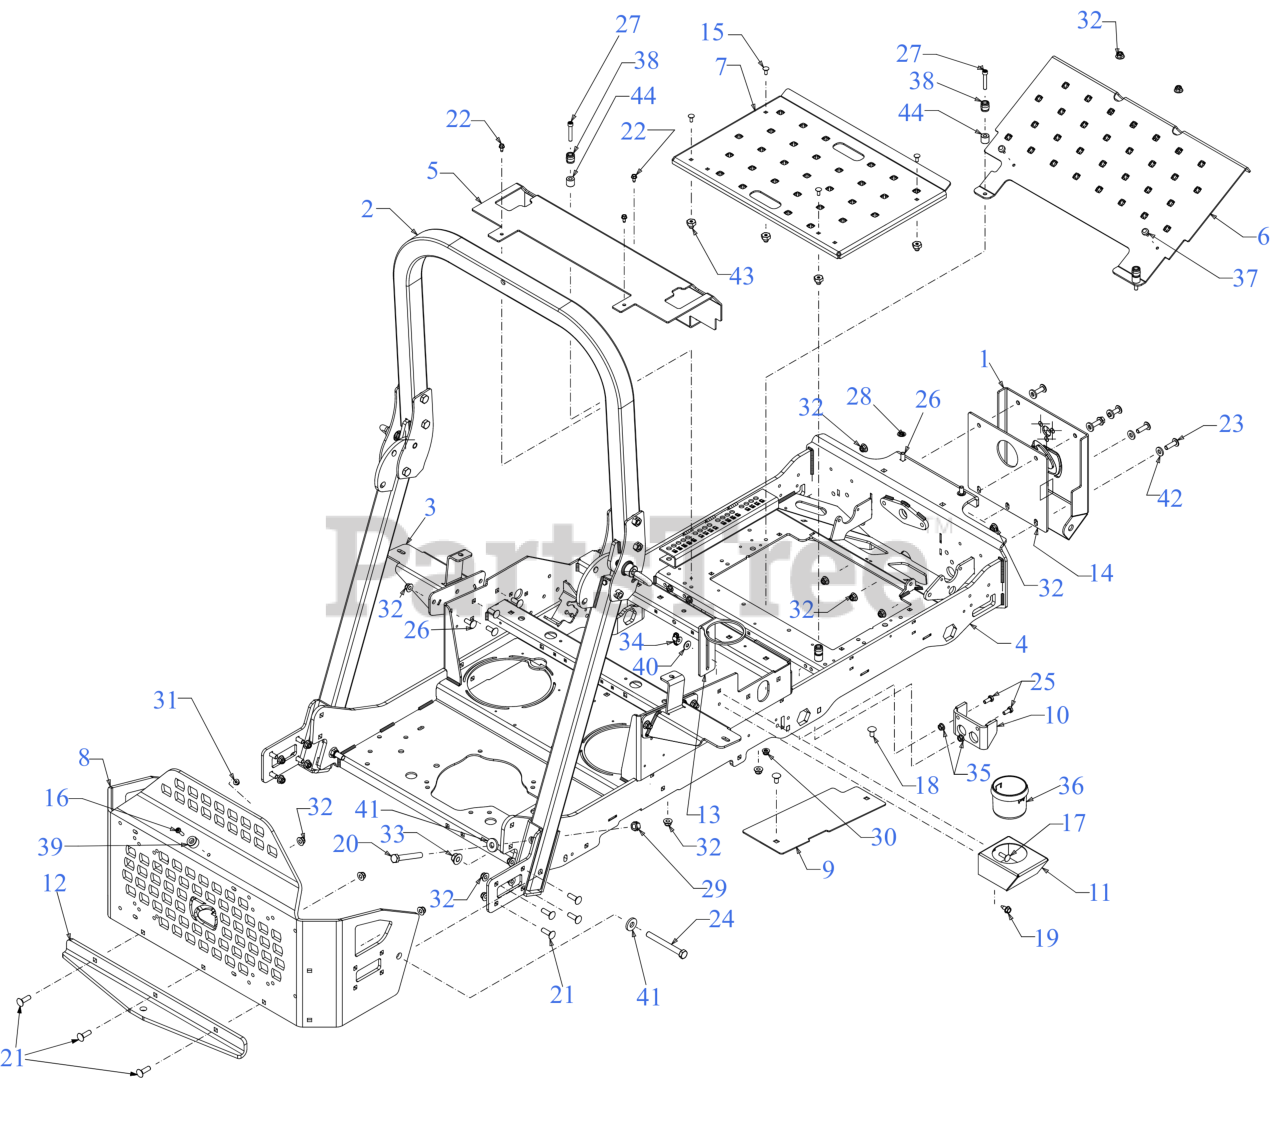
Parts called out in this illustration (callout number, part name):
2	PRO Z ROPS KIT
3	FUEL TANK MOUNT
4	FRAME ASSEMBLY
8	REAR BUMPER
14	FRONT MOUNTING PLATE SPACER
15	CARRIAGE BOLT 1/4-20 x .62
16	MACHINE SCREW 1/4-20:1
17	CARRIAGE BOLT 5/16-18 x 1.00
18	CARRIAGE BOLT 3/8-16 x .750 GR5
19	SCREW 5/16-18 x .750
20	SCREW 1/2-20 x 3.50 GR5
21	CARRIAGE BOLT 3/8-16 X1.25 GR5
22	SCREW 1/4-20 X.500
23	SCREW 3/8-16 x 1.25 GR5
24	SCREW 1/2-13 x 4.5 GR 5
25	SCREW 5/16-18 x .75 GR5
26	CARRIAGE BOLT 3/8-16 x 1.00 GR5
27	SCREW 5/16-18X1.75 GR5
30	FLANGE LOCK NUT 5/16-18
31	FLANGE LOCK NUT
34	WING NUT 5/16-18
35	FLANGE NUT
37	BUMPER, .62 DIA x .3
38	RADIAL BUMPER
40	FLAT WASHER
41	FLAT WASHER .531 x 1.25 x .181
42	FLAT WASHER
43	SHOULDER SPACER
